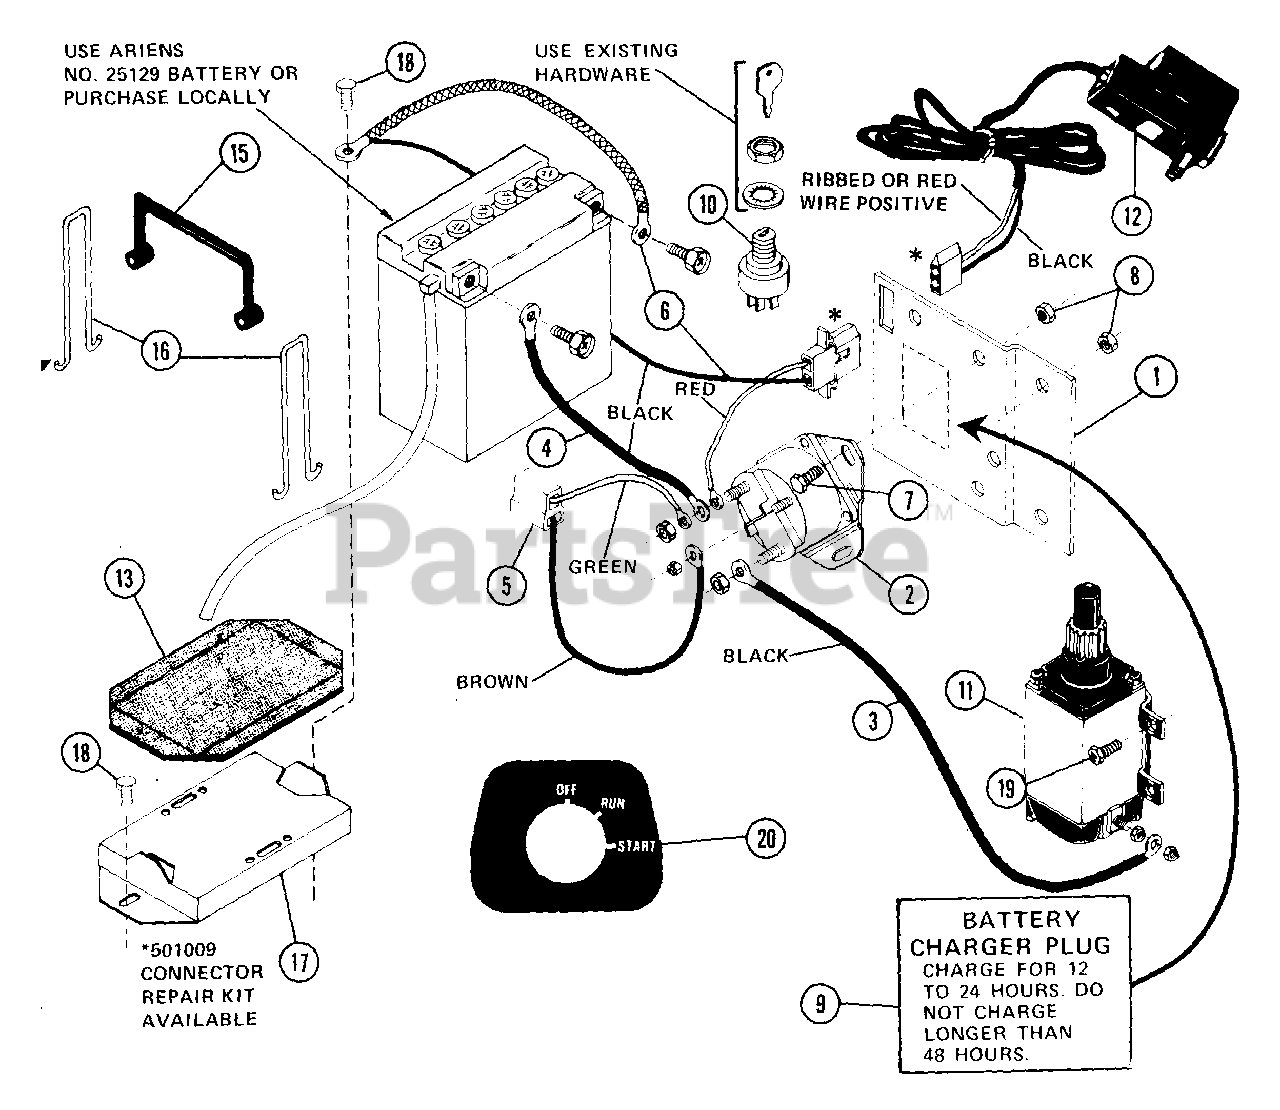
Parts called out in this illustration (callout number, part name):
1	BRACKET SOLENOID
2	SOLENOID,STARTER SWITCH
3	GROUND CABLE
4	BATTERY CABLE
5	WIRING HARNESS SWITCH
6	WIRING HARNESS BATTERY CHARGER
7	BLT-HEX .25-20X.50 PL GR2
8	NUT-LK-CTR .250-20 PL
9	DECAL CHARGING
10	KEY SWITCH
12	BATTERY CHARGER
13	RUBBER PAD
15	BATTERY STRAP
16	HOOK
17	BATTERY RETAINER
18	SCR-TAP 10-12X.50 CRPH PL A
19	SCR-CAP CR SEMS .25-20X.50 PL
20	DECAL SWITCH
